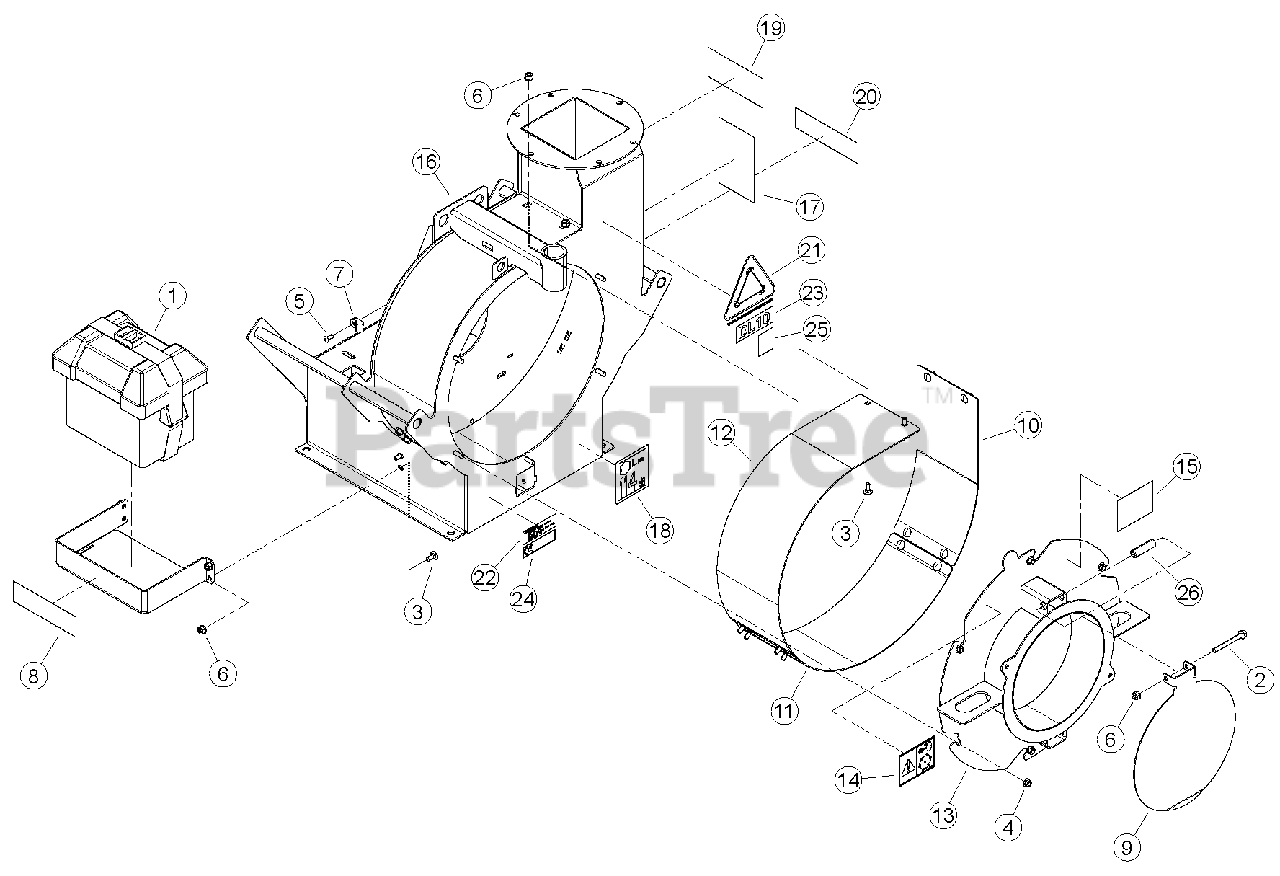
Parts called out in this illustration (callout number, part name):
1	BOX, SMALL BATTERY
2	BOLT, 5/16 X 3 FLANGE NC
3	BOLT, 5/16 X 3/4 GR5 NC ZP CRG
4	NUT, 5/16 FLANGE TOPLOCK
5	RIVET, AL BLIND 1/4 X 3/4 DOME HEAD
6	NUT, 5/16-18 NYLOCK-FLANGE
7	CLAMP, CABLE MOUNT
8	DECAL, ECHO BEARCAT 6.82 X 1.90
9	SHIELD, INTAKE
10	LINER, WEAR RIGHT
11	LINER, WEAR MIDDLE
12	LINER, WEAR LEFT
13	ASSEMBLY, VACUUM INTAKE
14	DECAL, INSTRUCTION ISO
15	DECAL, INSTRUCTION ISO
16	ASSEMBLY, DL10 HOUSING
17	DECAL, OPERATING INSTRUCTIONS ISO
18	DECAL, 114 DB
19	DECAL, MUTILINGUAL MANUAL
20	DECAL, ECHO BEARCAT 6.82 X 1.90
21	DECAL, COLLECT IT
22	DECAL, ATLANTIC BRIDGE LTD INFO
23	DECAL, MODEL DL10
24	DECAL, DL10 INFORMATION
25	DECAL, ECHO BEARCAT QR CODE
26	SPACER, 5/8 OD X 11 GA X 2.13
